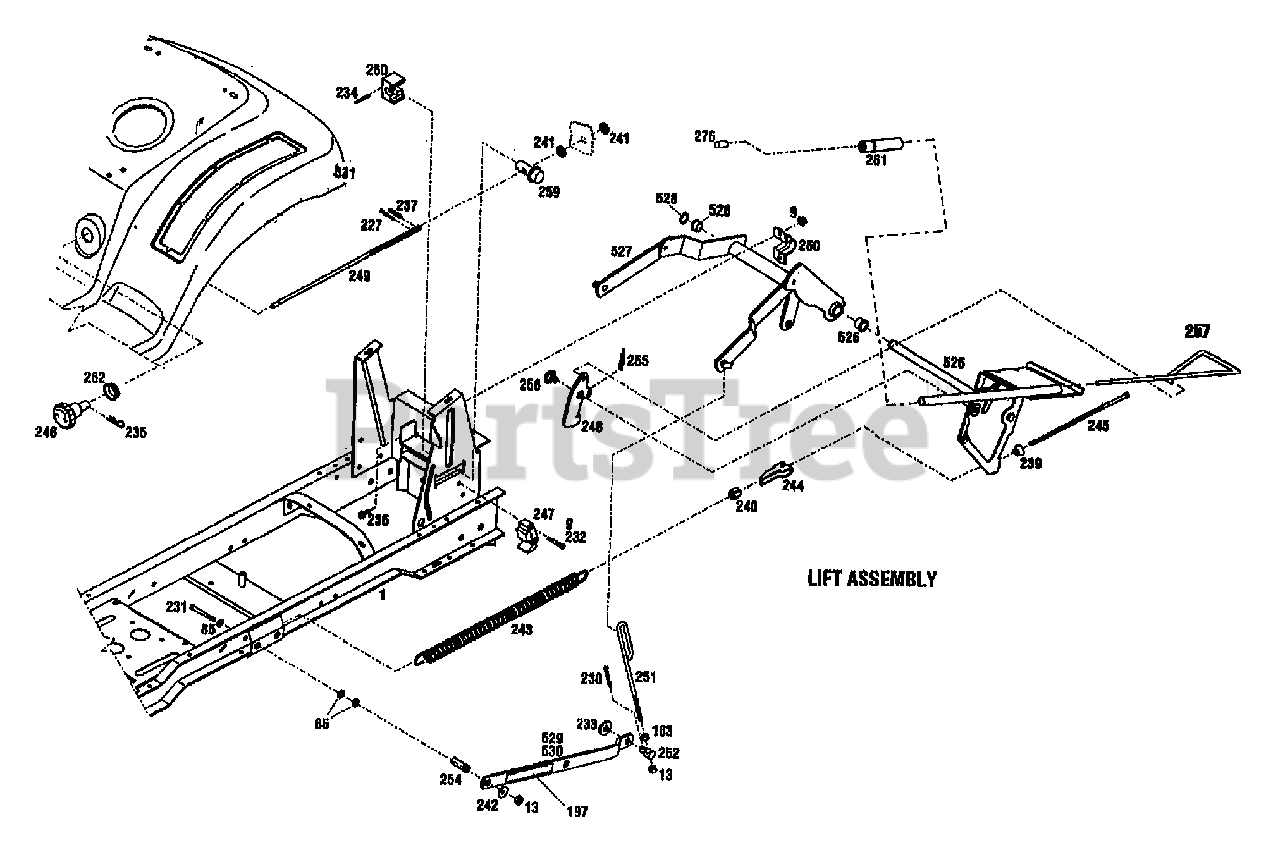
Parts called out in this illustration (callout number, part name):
9	NUT-HFLK 5/16-18 ZP
13	NUT-LOCK 3/8-16
85	WASHER-FLAT 3/8 SAE
163	NUT-HEX 3/8-16 ZP
197	DECAL-WARNING
227	PIN-COTTER .125 X .75 ZP
230	PIN-COTTER .120X1.25 ZP
231	SCR-HH 3/8-16X3.0 G5 ZP
232	SCR-HH 5/16-18X1.5 G5 ZP
234	PIN-DRIVE
235	PIN-HITCH
236	SCR-HFLK 5/16-18X.75 ZP
237	PIN-ROLL .156X1.0
239	BEARING-SPHERICAL
240	NUT-SPECIAL 5/16-18
242	WASHER-1.5X.375X.18 ZP
243	SPRING-LIFT ASSIST
244	BRKT-LIFT ASSIST
245	SCR-LIFT ASSIST
246	KNOB-HEIGHT ADJUST
247	BLOCK-DETENT
249	KIT-SVC SCR HGT ADJ
250	CLAMP-LIFT
251	ROD-LIFT
252	SWIVEL-LIFT REAR
254	SPACER
255	SPRING-EXTENSION
256	SCR-SHOULDER
259	BLOCK-HEIGHT ADJUST
260	COLLAR-HEIGHT ADJUST
261	GRIP-LIFT
262	GROMMET-SNAP BUSHING
276	BUTTON-LIFT
525	HANDLE-LIFT
528	RING-RETAINING EXT .694 ID
